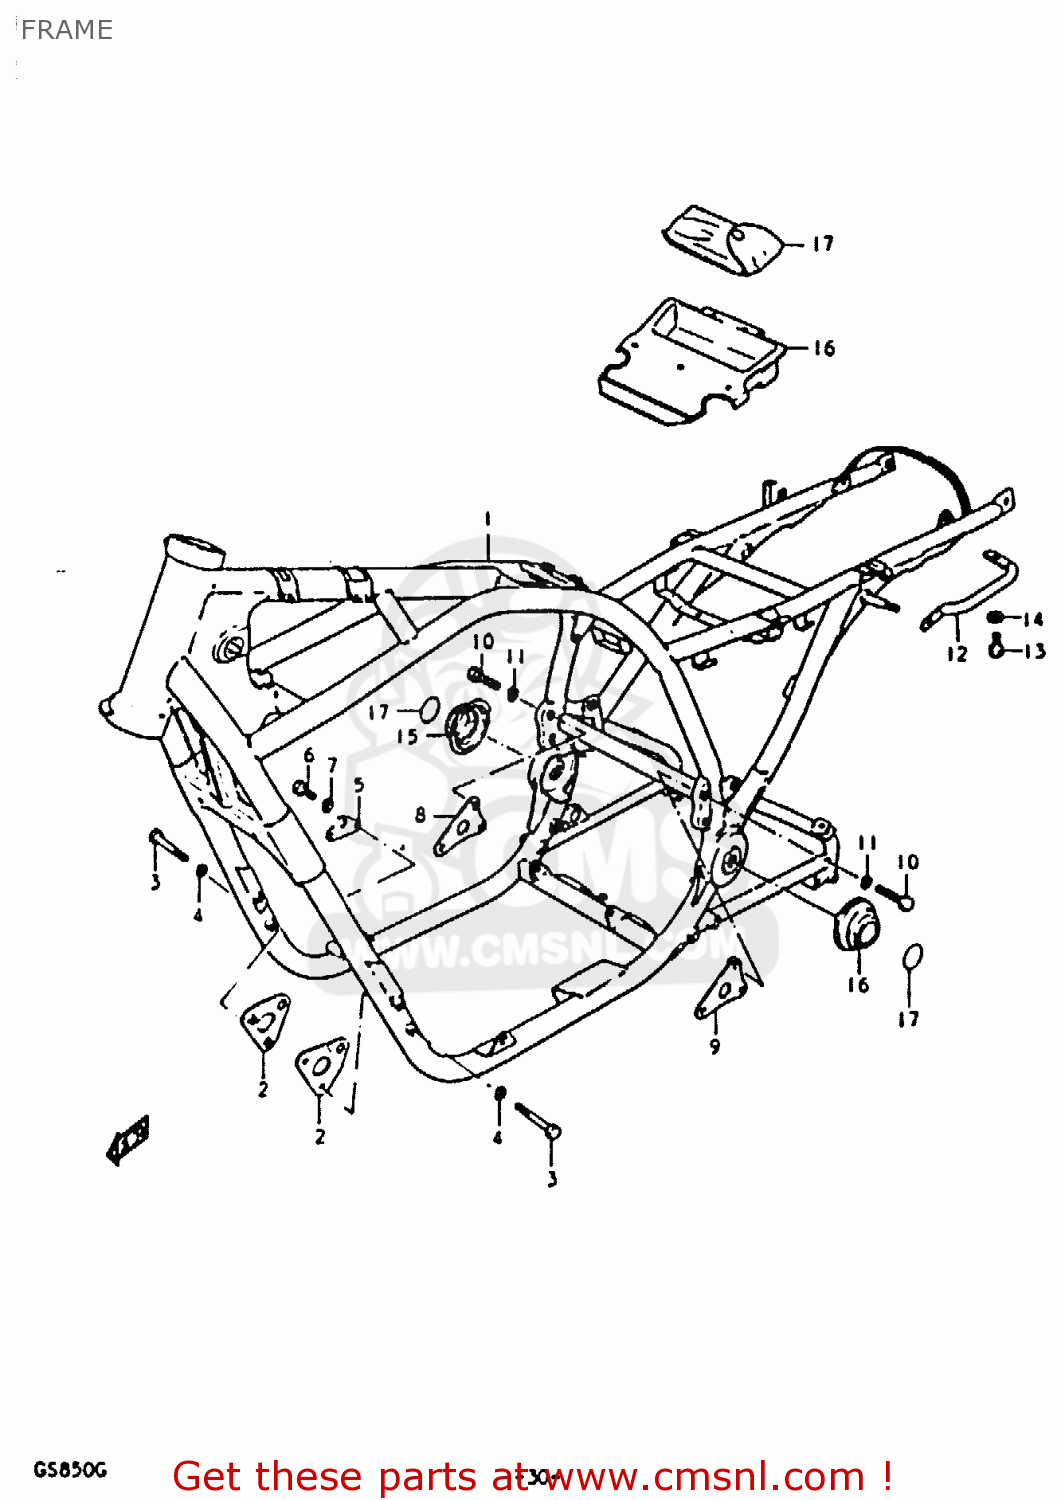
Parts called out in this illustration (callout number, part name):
1	FRAME
2	PLATE,ENGINE MOUNTING
3	BOLT
4	LOCK WASHER
5	PLATE,ENGINE MOUNTING
6	BOLT
7	LOCK WASHER
8	PLATE,ENGINE MOUNTING
9	PLATE,ENGINE MOUNTING
10	BOLT 8X40
11	LOCK WASHER
12	GRIP,FRAME
13	BOLT
14	WASHER
15	COVER,REAR SWING ARM PIVOT
16	COVER,REAR SWING ARM PIVOT
17	EMBLEM,FRAME COVER
18	HOLDER,TOOL
19	TOOL SET
